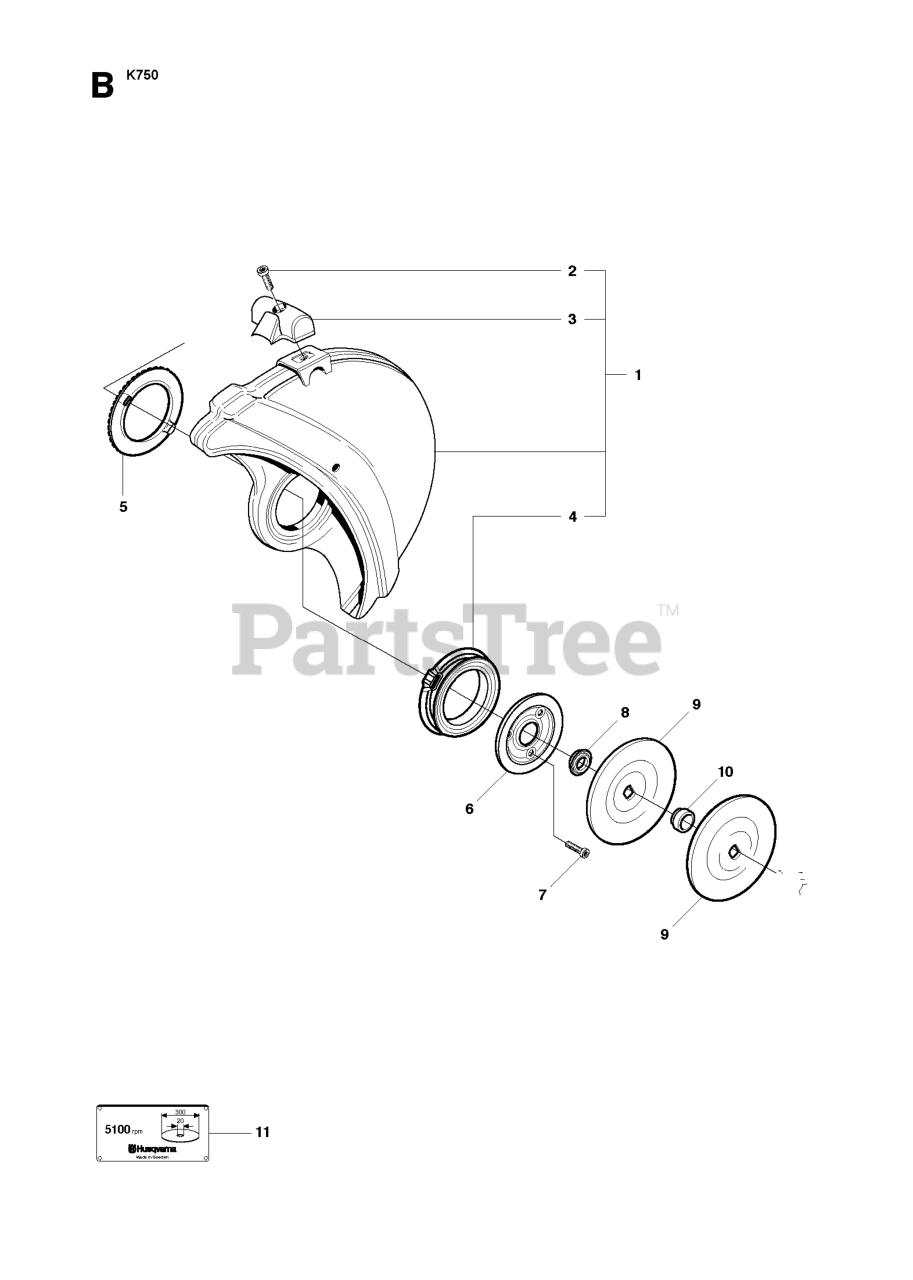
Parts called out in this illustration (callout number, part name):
1	WHEEL GUARD ASSY
1	WHEEL GUARD ASSY, 12" GREY
7	SCREW ITXSCM
9	WASHER
10	BUSHING-30MM
11	ARBOR SIZE DECAL/20
11	ARBOR SIZE DECAL/25.4
